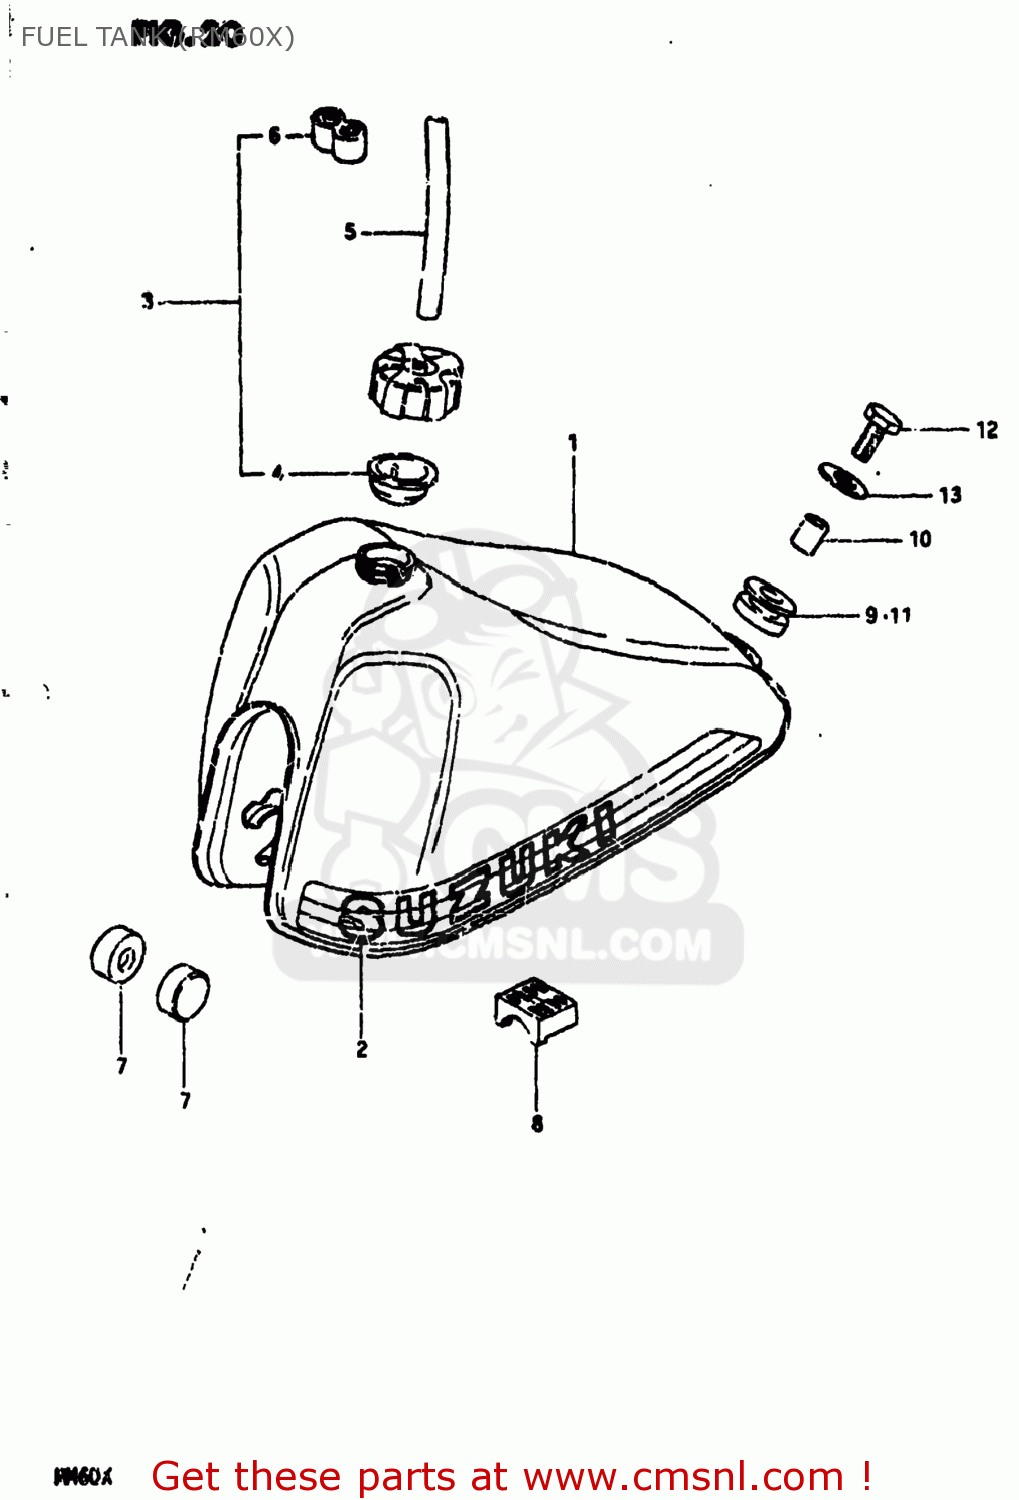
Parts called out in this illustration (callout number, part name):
1	TANK ASSEMBLY,FUEL
2	TAPE SET,FUEL TANK
3	CAP ASSEMBLY,FUEL TANK
4	GASKET,FUEL TANK CAP
5	HOSE
6	CLAMP,FUEL TANK BREATHER HOSE
7	CUSHION
8	CUSHION,FUEL TANK
9	CUSHION
10	SPACER (8.8X12X13.5)
11	CUSHION
12	BOLT
13	WASHER (8.5X29X1.6)
